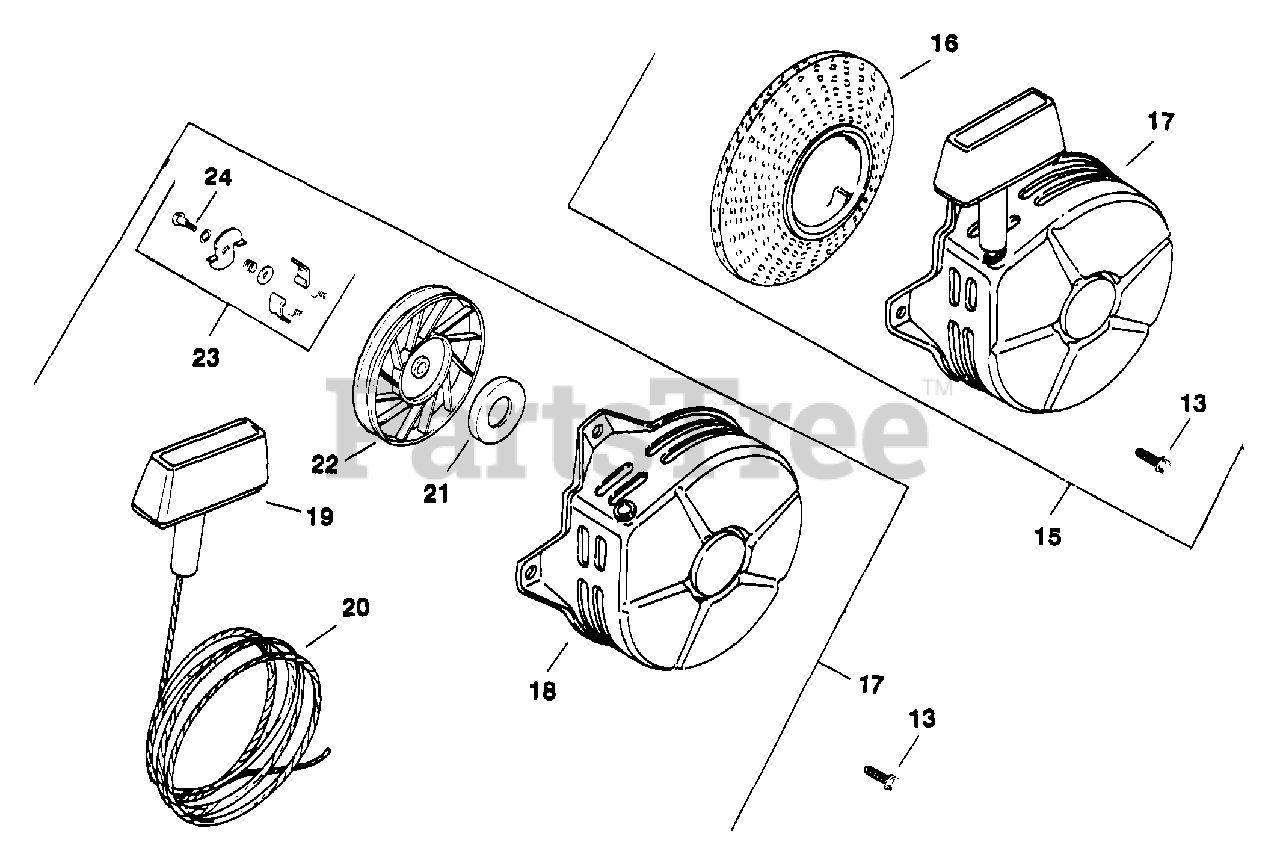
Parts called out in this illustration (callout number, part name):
13	SCREW, FLG HD 10-24X1/4"
15	KIT, STARTER W/CUP - DISCONTINUED
16	CUP W/SCREEN
17	STARTER, RECOIL - DISCONTINUED
19	HANDLE - USE 234452
20	ROPE - DISCONTINUED
21	SPRING & KEEPER - (#DSC)
22	PULLEY - (#DSC)
23	KIT, DOG REPAIR - (#DSC)
24	SCREW - DISCONTINUED
